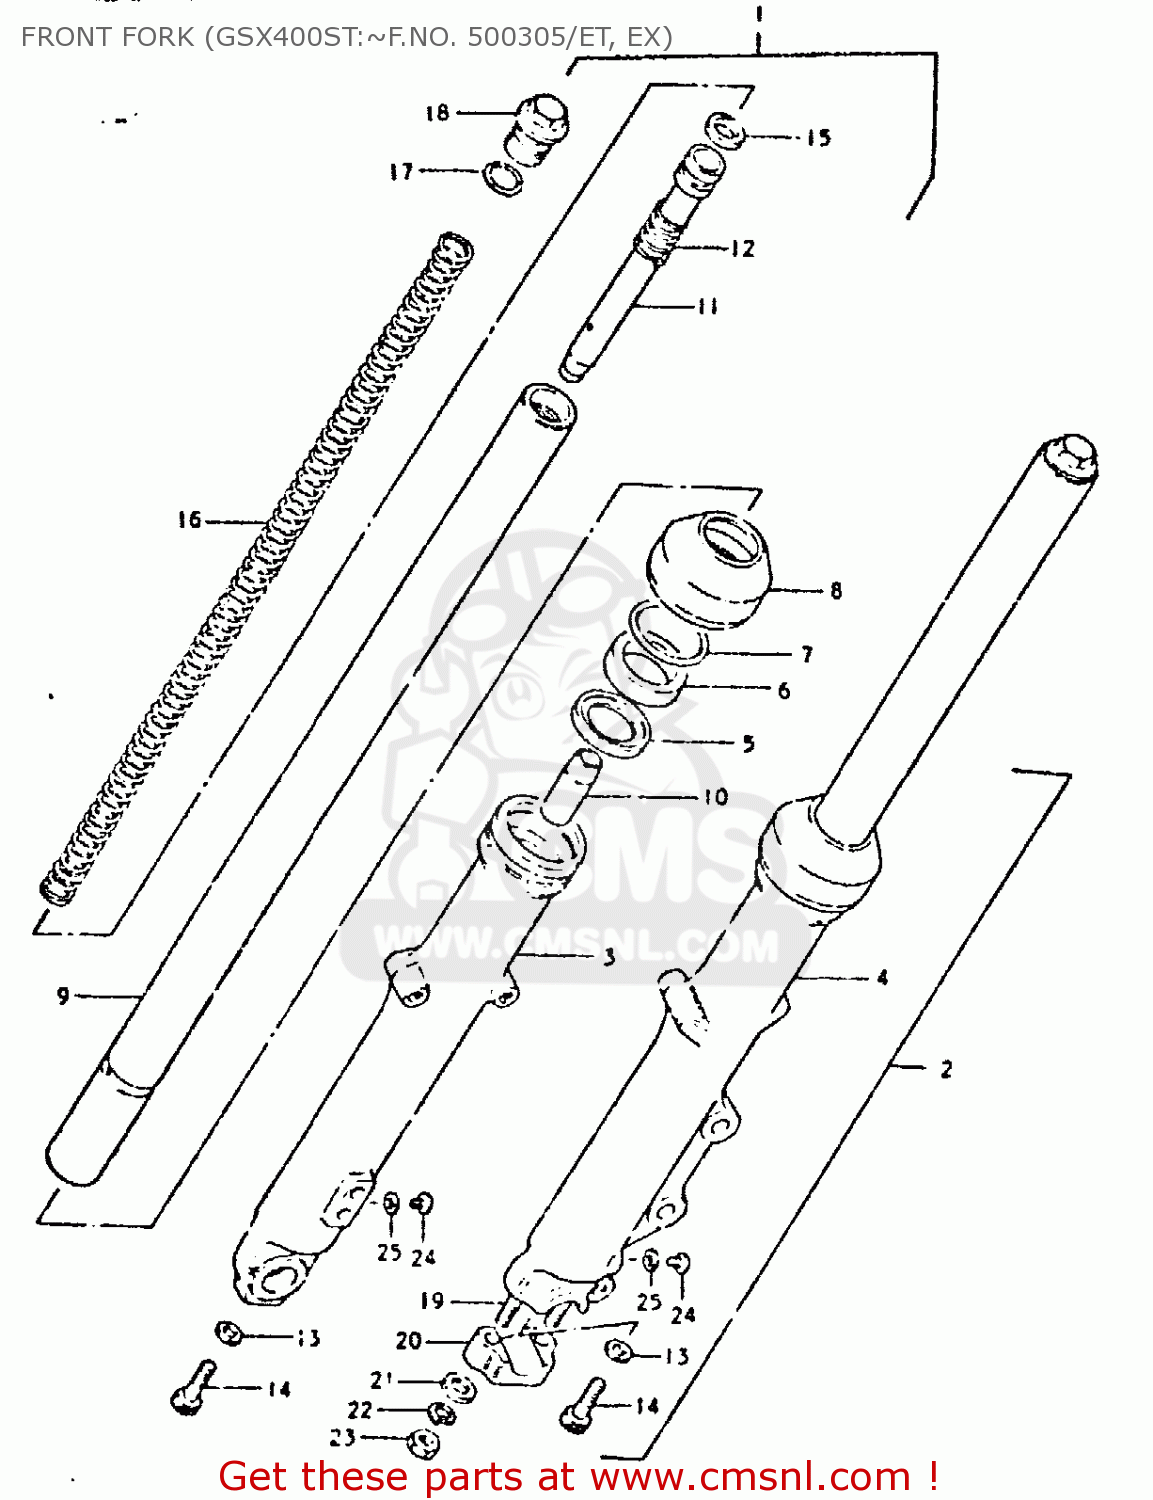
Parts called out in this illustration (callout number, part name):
1	DUMPER ASSY, RH
2	DUMPER ASSY, LH
3	TUBE,FORK,OUTER,RIGHT
4	TUBE,FORK,LEFT,OUTER
5	SPACER,OIL SEAL
6	OIL SEAL,FRONT FORK
7	CIRCLIP,FORK OIL SEAL
8	BOOT
9	TUBE,INNER
10	PIECE,OIL LOCK
11	PIPE, SEAT
12	SPRING,REBOUND
13	GASKET (NAS)
14	BOLT(8X27)
15	RING,PISTON
16	SPRING
17	O RING
18	BOLT
19	STUD 8X25
20	HOLDER,AXLE
21	WASHER
22	LOCK WASHER
23	NUT (8MM)
24	SCREW 4X6
25	GASKET (NAS)
